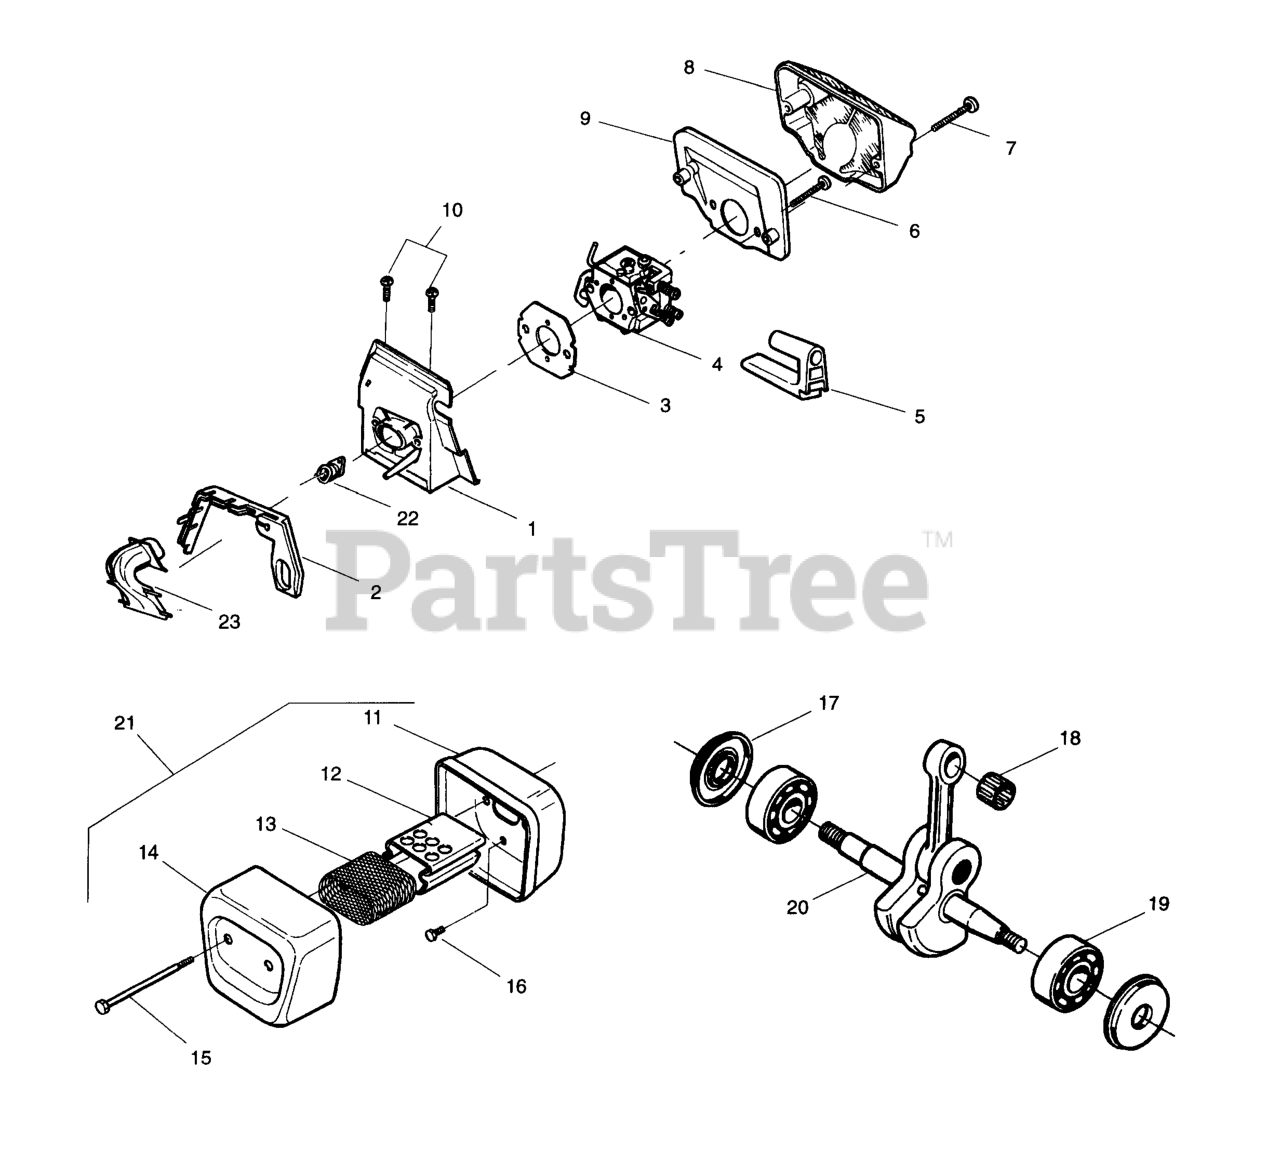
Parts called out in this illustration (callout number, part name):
1	CARB ADAPTOR
2	TURBO CLEAN SEAL
3	GSKT,CARB 36/41
4	CARBURETOR WT350
5	GROMMET
6	STUD-CARBURETOR
8	AIR FILTER
9	AIR FILTER (BOTTOM)
10	SCREW,REAR HBAR 36/41
11	SILENCER BODY
12	FLAME PROTECTOR
13	SPARK ARRESTOR 36/41
14	SILENCER COVER
16	BOLT-MUFFLER(SUPPORT)
17	SEAL,C/SHAFT 36/41
18	Piston Pin Bearing
19	Crankshaft Bearing
20	CRANKSHAFT ASSY 36/41
21	MUFFLER KIT
22	INTAKE PIPE
23	INTAKE HORN
